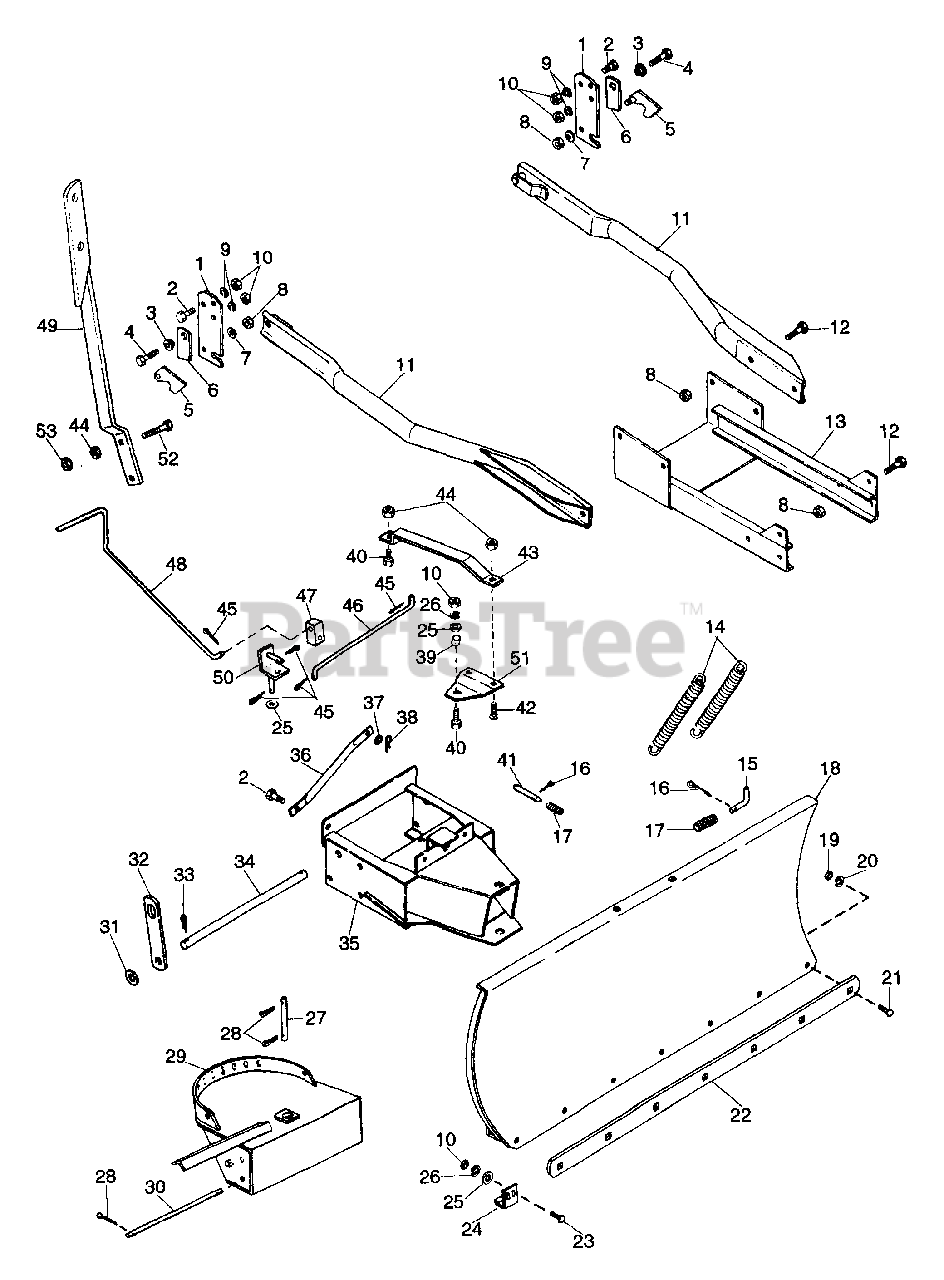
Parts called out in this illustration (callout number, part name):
1	REAR HANGER
2	BLT-HEX .38-16X1.00 PL GR5
3	SPACER .400X.625X.400X.875
4	BLT-HEX .38-16X1.50 PL GR5
5	LATCH RH
6	LOCK STOP
7	SPRING WASHER
8	NUT-LK TOP .375-16 GR C YWZC
9	WSHR-LK .375X.115 HVY PL
10	NUT-HEX .375-16
11	REAR ATTACHMENT BRACE
12	BLT-HEX .38-16X.75 PL GR5
13	CHANNEL-CROSS
14	SG-TENS .187X1.50X9.94 WLD 40
15	JACK PIN
16	PIN-COTR .12X1.0 PL
17	SG-COMP .080X.85X1.44
18	BLADE 42 INCH
19	NUT-HEX .312-18
20	WSHR-LK .312X.097 PL HVY
21	BLT-RDHDSQNK .31-18X1.00 PL
22	WEAR PLATE
23	BLT-RDHDSQNK .38-16X1.0 PL
24	SKID SHOE
25	WSHR-FL-STL .438X1.0X.083 PL
26	WSHR-LK .375X.094 MED PL
28	PIN-COTR .18X1.0 PL
29	SUPPORT
31	WSHR-FL-STL.656X1.312X.095 PL
32	LIFT LINK
33	PIN-HAIR EXT .12X.31X2.37 PL
34	PIVOT ROD
35	FRAME HTH BLADE
37	WSHR-FL-STL .390X.750X.125 PL
38	PIN-HAIR INT .09X.188 PL
39	SPACER .406X.749X.162
40	BLT-HEX .31-18X1.25 PL GR2
41	LATCH PIN
42	BLT-RDHDSQNK .31-18X.75 SHT PL
44	NUT-LK .312-18 GR A PL
45	PIN-COTR .12X.75 PL
47	UNIVERSAL BLOCK JOINT
49	CHUTE CRANK SUPPORT
51	PIVOT PLATE
52	BLT-HEX .31-18X1.50 GR2 YWZC
53	NUT-FLG. .312-18 PL
